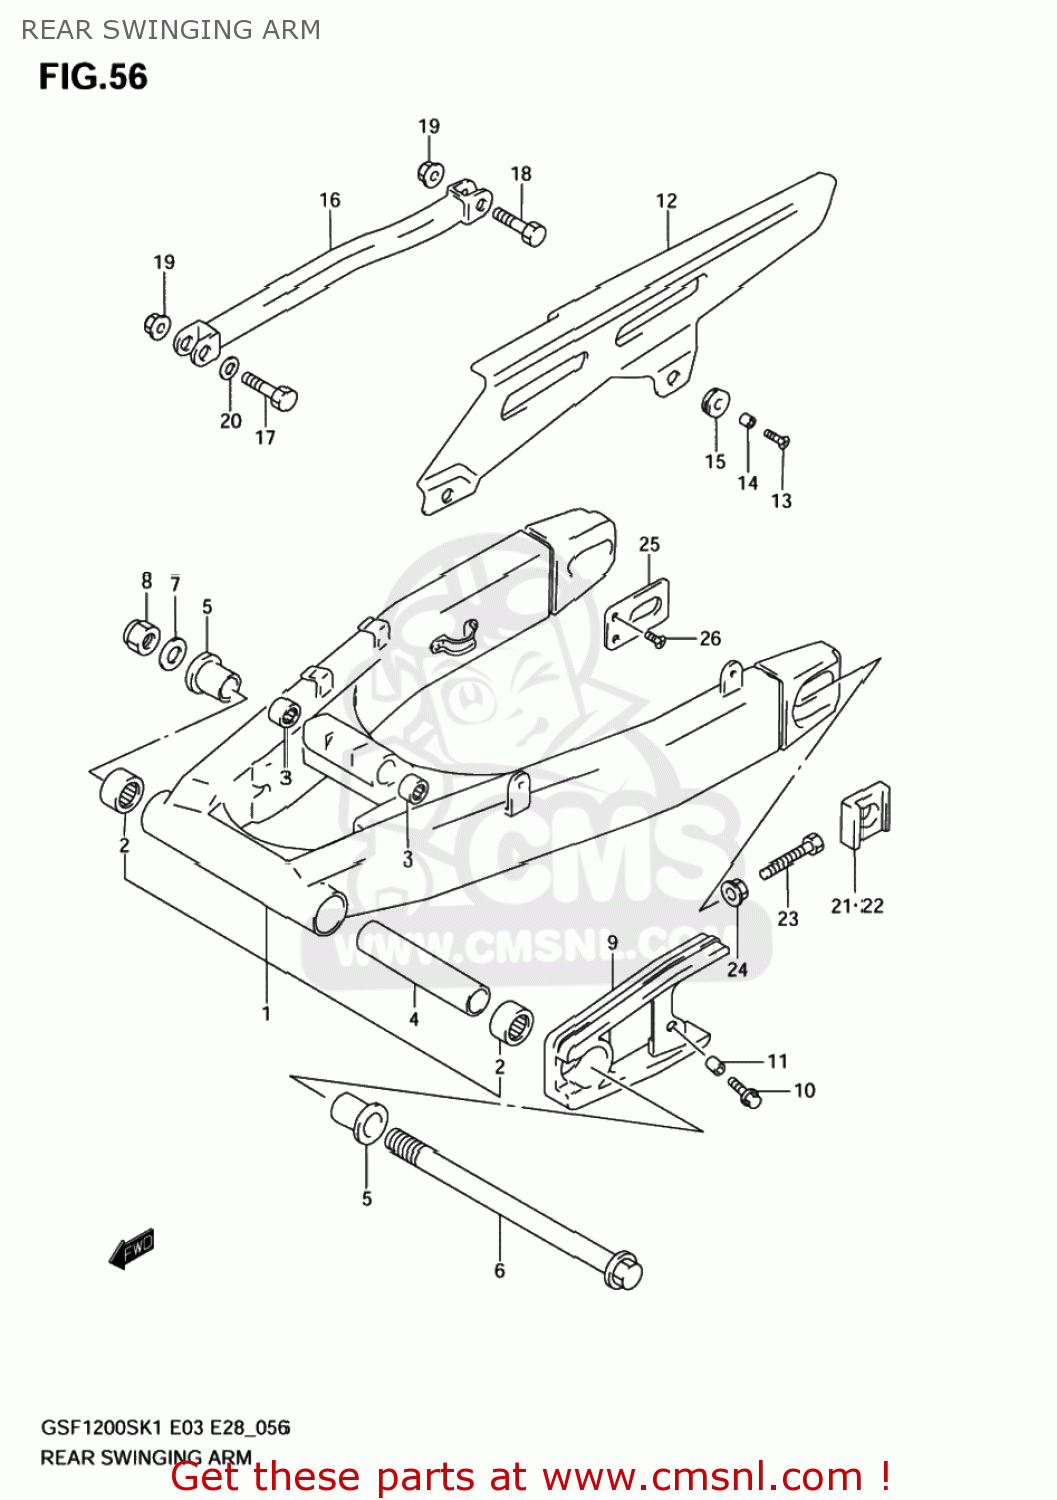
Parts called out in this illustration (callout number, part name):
1	SWINGINGARM ASSY,RR
2	BEARING(25X33X35)
3	BEARING(17X24X25)
4	SPACER,RR SWGARM PIVOT CTR
5	SPACER,RR SWGARM PIVOT BERRING
6	SHAFT,RR SWINGINGARM PIVOT
7	WASHER(18.5X28X2.6)
8	NUT
9	BUFFER,CHAIN TOUCH DEFENSE
10	BOLT(6X20)
11	SPACER(6.5X10X7)
12	CASE,CHAIN
13	SCREW (6X16)
14	SPACER(6.2X8.3X6.1)
15	CUSHION
16	TORQUELINK,RR
17	BOLT(10X39)
18	BOLT(10X37)
19	NUT
20	WASHER(12.5X20X1)
21	WASHER,CHAIN ADJUSTER
22	WASHER,CHAIN ADJUSTER
23	BOLT(8X50)
24	NUT
25	PLATE,RR SWING ARM BRKT
26	SCREW
